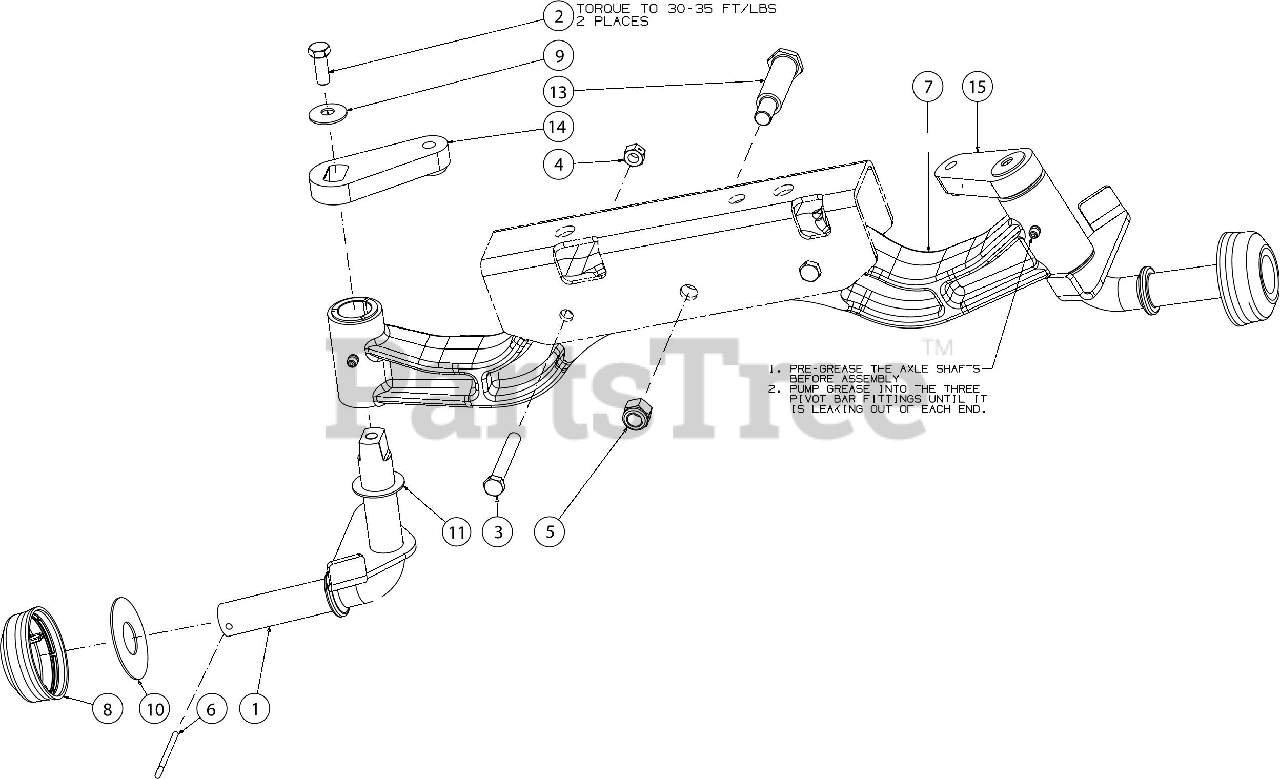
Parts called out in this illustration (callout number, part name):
1	FRONT AXLE ASSEMBLY
2	SCREW 3/8-24 x 1.00 GR5
3	SCREW 3/8-16 x 2.75 GR8
5	HEX LOCK NUT NYLON
6	COTTER PIN
8	CASTER AXLE CAP
9	BELL WASHER .390x1.130x.062
10	FLAT WASHER 1.05X2.50X.060
11	WASHER 1.010X1.560X.060
13	SHOULDER SCREW
14	STEERING ARM (LH)
15	STEERING ARM (RH)
